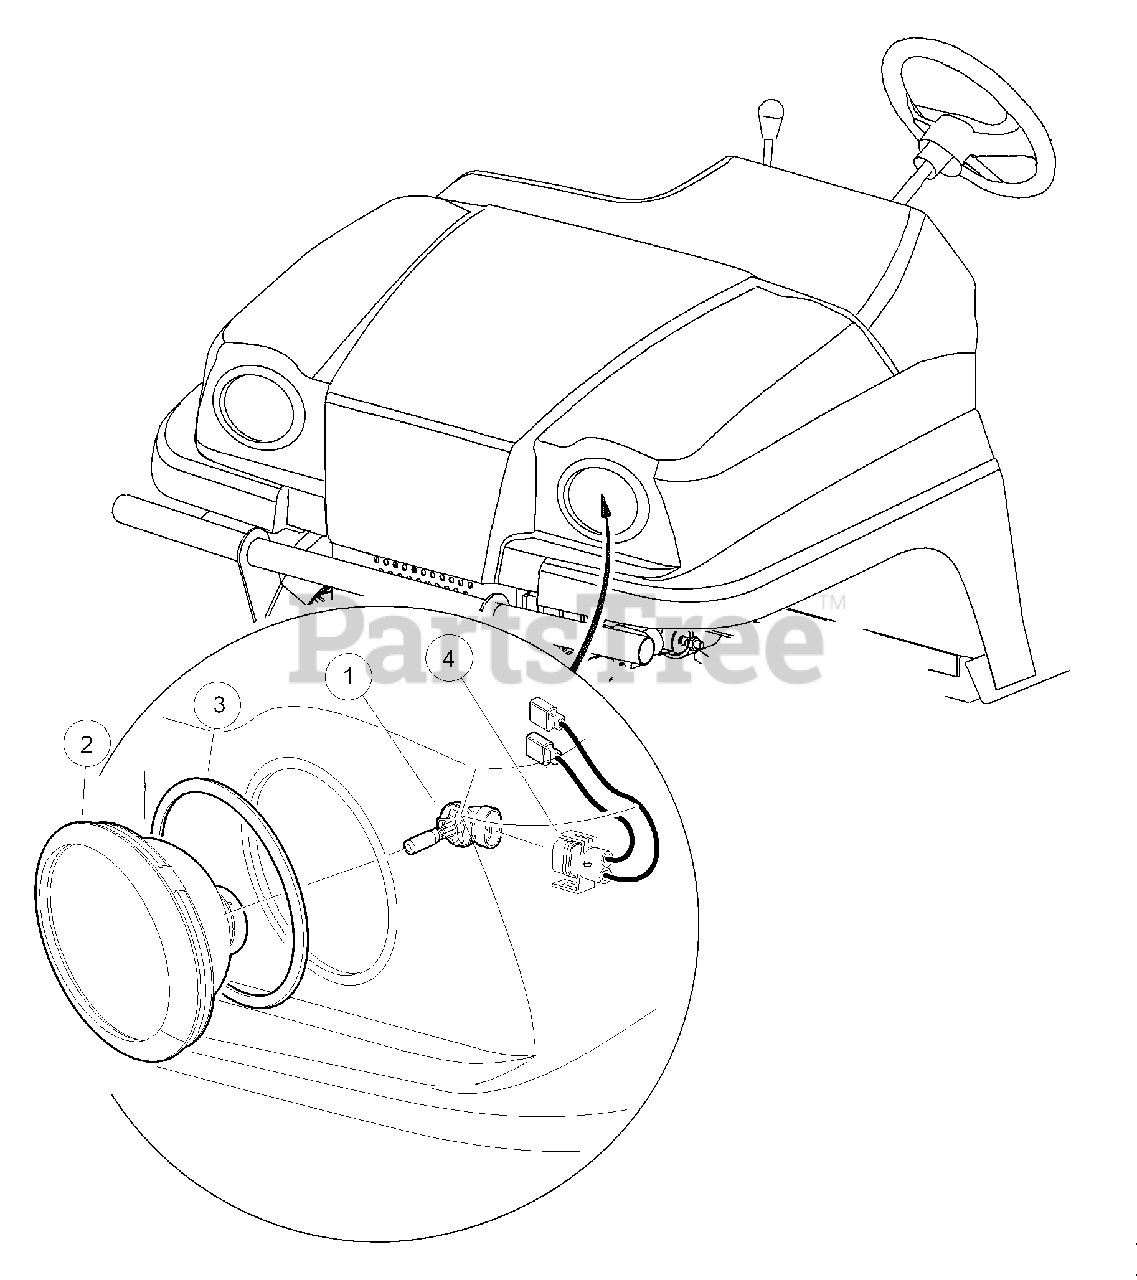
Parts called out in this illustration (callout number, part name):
1	Assembly, Headlight
2	Spacer, Headlight, Oval
3	Harness, Headlight
4	Bulb, Headlight, Oval
